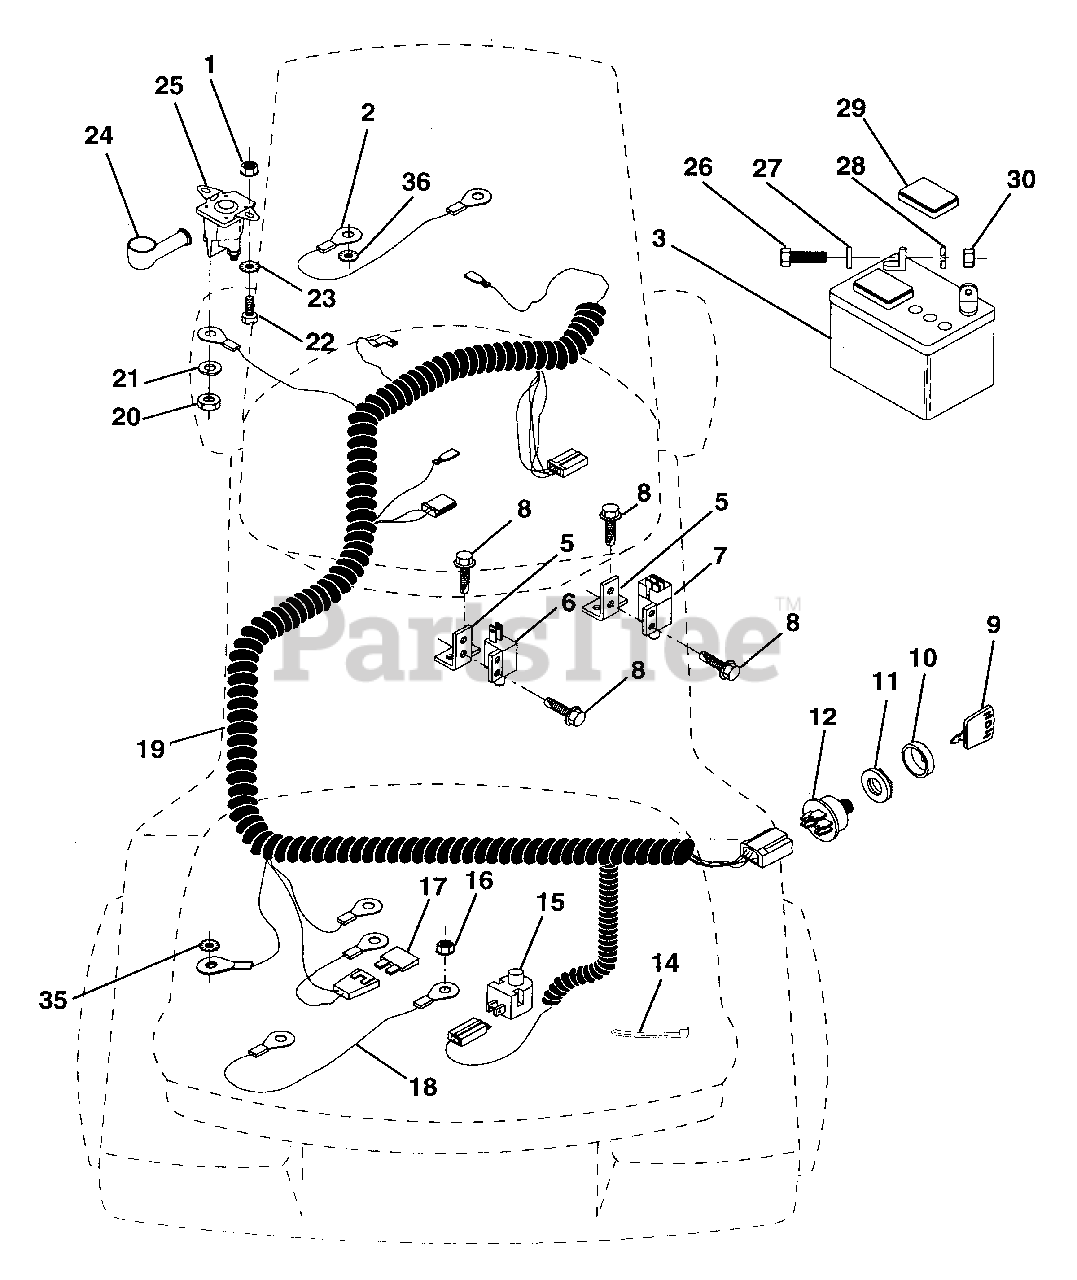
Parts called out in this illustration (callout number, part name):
1	Nut, Hex, Keps 1/4-20
2	Assembly, Cable
3	Battery
5	Bracket, Switch
6	Switch, Interlock
7	Switch, Interlock
8	Screw, Hex Washer Head, Self-Tapping #10-24 x 1/2
9	Key, Molded
10	Cover, Ignition Key
11	Nut, Ignition
12	Switch, Ignition
14	Tie, Cable
15	Switch, Plunger
16	Nut, Hex, Keps 5/16-18
18	Assembly, Cable
19	Harness, Ignition
20	Nut, Hex, Jam 1/4-20
21	Washer, Lock 1/4
22	Bolt, Hex, Fin. 1/4-20 UNC x 1/2 Grade 5
23	Washer, Lock, External Tooth 1/4
24	Cover, Terminal
25	Solenoid
26	Bolt, Hex Head 1/4-20 UNC x 3/4
27	Washer 9/32 x 5/8 x 16
28	Washer, Lock 1/4
29	Cap, Battery
30	Nut, Hex, Fin. 1/4-20 UNC
35	Washer, Lock, External Tooth 3/8
